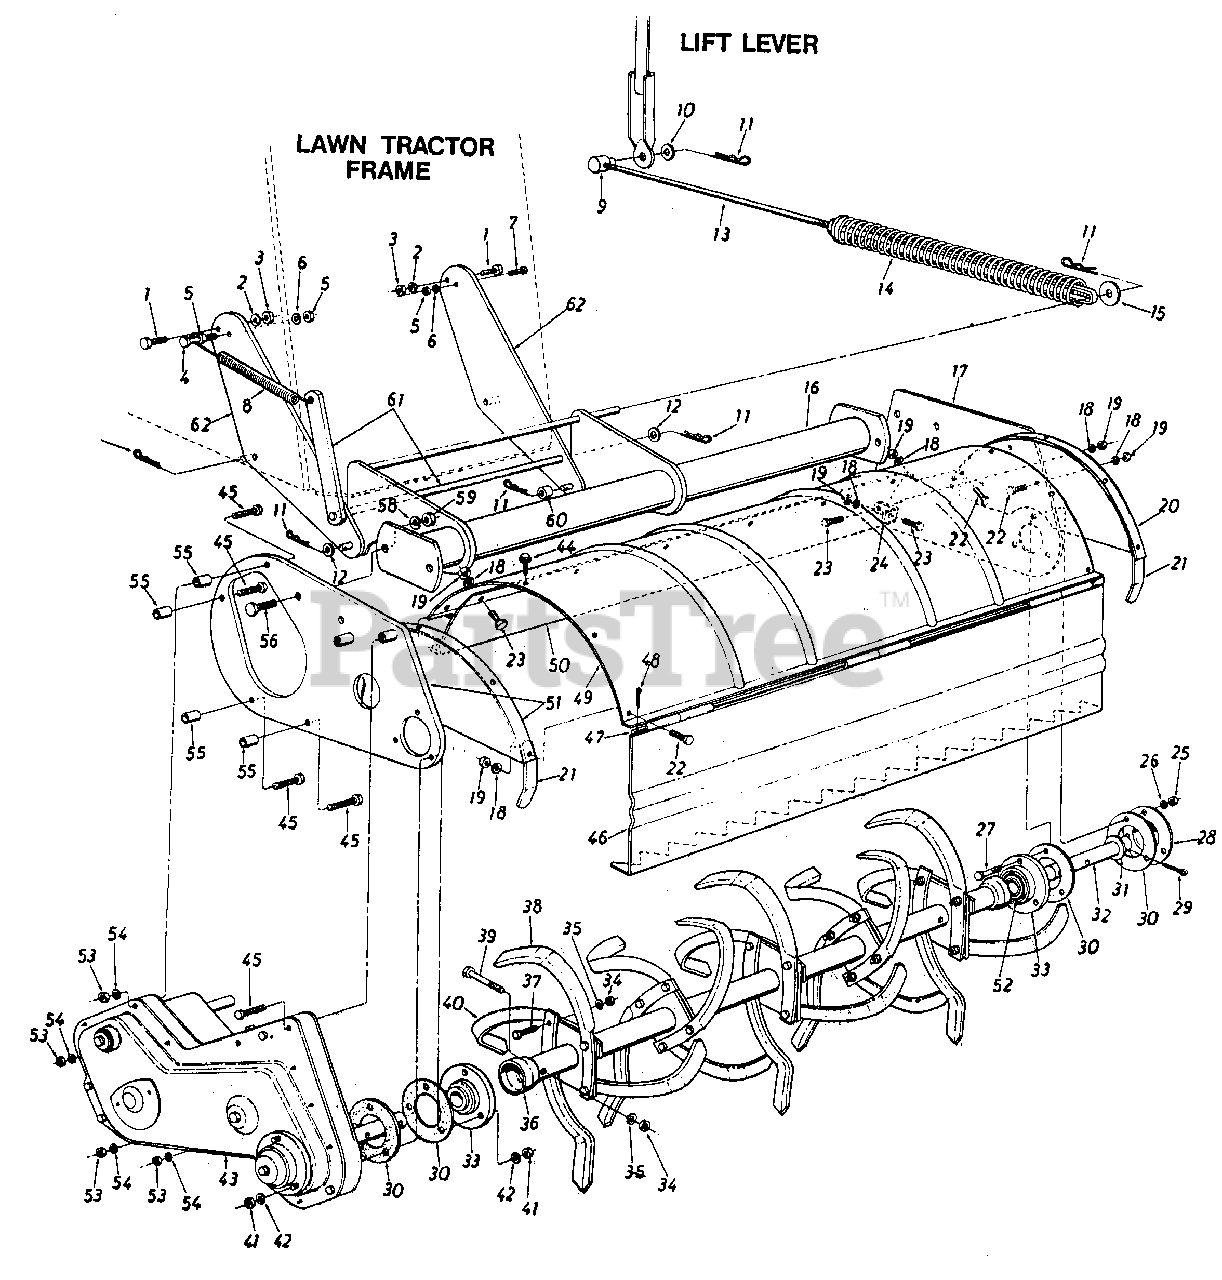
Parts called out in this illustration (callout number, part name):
1	Hex Bolt 3/8-24x .88" Lg.*
2	L.-Wash. 3/8" I.D. Heavy Duty
3	Hex Nut3/8-24Thd.*
4	Hex Bolt 5/16-24 x 1.50" Lg.*
5	Hex Nut 5/16-24 Thd.*
6	L.-Wash. 5/16" I.D.*
7	Hex Bolt 5/16-24 x 1.00" Lg.*
8	Extension Spring .56" O.D. x 7.75" Lg.
9	Adjustment Ferrule 1/2-13 Thd .
10	Fl.-Wash. .640" I.D. x 1.24" O.D. x.060
11	Intern. Cotter Pin 1/2" Dia.
12	Fl.-Wash. .510" I.D. x 1.0" O.D. x .060
13	Lift Rod Ass'y. 39.0" Lg.
14	Compression Spring 1.50" O.D. x 15.0" Lg.
15	Fl.-Wash. .51" I.D. x 1.50" O.D. x .075
16	Pivot Bracket Assembly
19	Hex Nut 5/16-24 Thd.*
23	Hex Bolt 5/16-24 x .62" Lg.*
24	Chute Pivot B racket
25	Hex Cent. L-Nut 5/16-18 Thd.
26	L.-Wash. 5/16" I.D.*
27	Hex Bolt 5/16-18 x 1.0" Lg. (Grade 5)
30	Gasket for Brg. Housing
31	Fl.-Wash. 1.25" I.D. x 2.00" O.D. x . 06
32	Tine Shaft R.D. 1.25" Dia. x 6.25" Lg.
33	Bearing Housing w/ Bearing
34	Hex Nut 3/8-24 Thd.*
35	L.-Wash. 3/8" I.D. Heavy Duty
41	Hex Cent. L.-Nut 5/16-18 Thd.
42	L.-Wash. 5/16" I.D.*
43	Chain Case Ass'y. Comp.
44	Hex Wash. TT Tap. Scr. 5/16-18 x .62" Lg.
45	Hex Bolt 1/4-20 x 2.75" Lg.*
48	Cotter Pin 1/8" Dia. x 1.00" Lg.*
53	Hex Nut 1/4-20Thd.*
54	L.-Wash. 1/4" I.D.*
55	Spacer.28" I.D. x .62" O.D. x
56	Hex Bolt 1/2-13 x 1.00" Lg.*
58	L.-Wash. 1/2" I.D.*
59	Hex Nut 1/2-13 Thd.*
60	Spacer.50" I.D. x 1.00" O.D. x.50" Lg.
61	Idler Bracket Support Arm Ass'y.
62	Pivot Bracket Support
